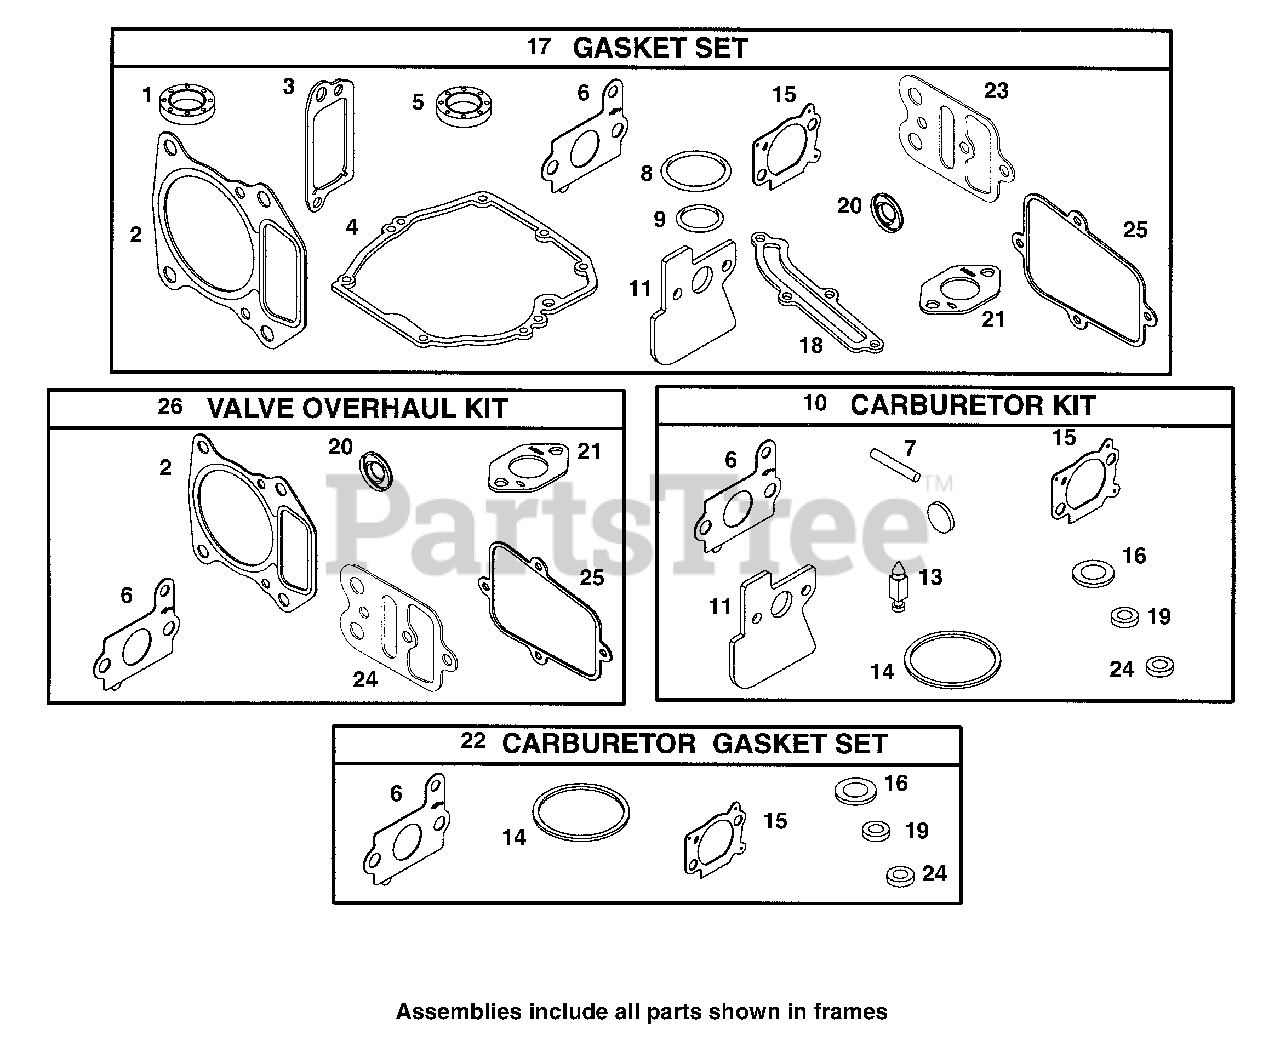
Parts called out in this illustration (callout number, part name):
1	Oil Seal
2	Cylinder Head Gasket
3	Breather Gasket
4	Crankcase Gasket
5	Oil Seal
6	Intake Gasket
7	Float Hinge Pin
8	Seal-O-Ring
9	Seal-O-Ring
10	Carburetor Kit
11	Carburetor Spacer
13	Needle Valve
14	Float
15	Air Cleaner Gasket
16	Seal Washer
17	Gasket Set
18	Breather Passage Gasket
19	Choke Shaft Seal
20	Valve Seal
21	Exhaust Gasket
22	Carb. Gasket Set
23	Throttle Shaft Gasket Seal
24	Throttle Shaft Seal
25	Rocker Cover Gasket
26	Valve Overhaul Kit
